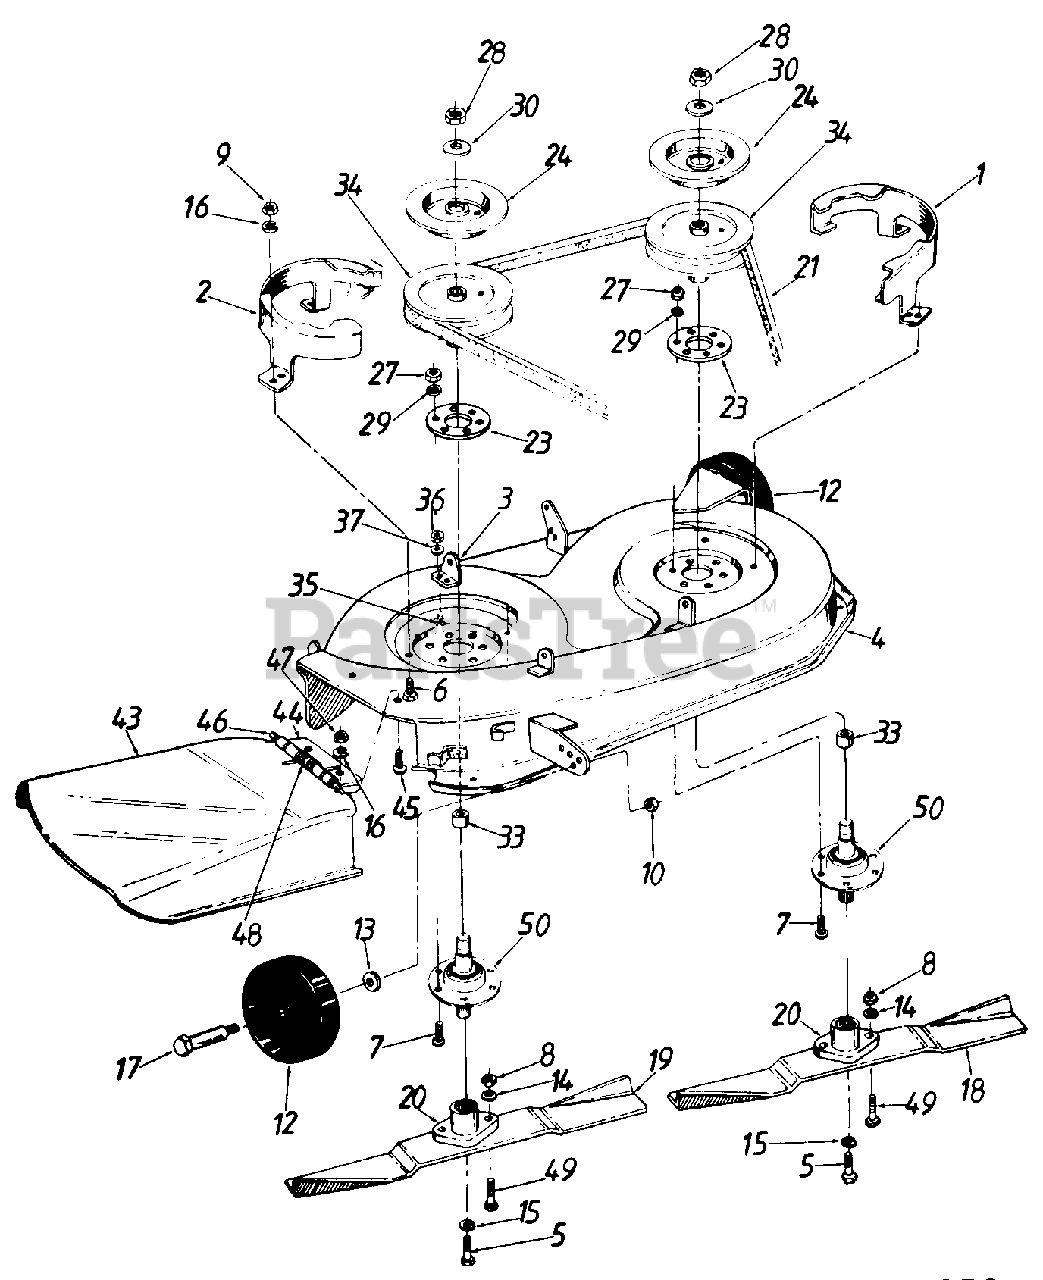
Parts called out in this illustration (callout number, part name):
5	Hex Bolt 3/8-24 x 1.0" Lg.
6	Hex Bolt 1/4-28 x .62" Lg.
7	Rib Neck Bolt
8	Hex Nut 5/16-24 Thd.
9	Hex Nut 1/4-28 Thd.
10	Hex L-Nut 3/8-16 Thd.
12	Deck Wheel
13	Bell-Wash. .380" I.D. x .88
14	L-Wash. 5/16" I.D.
15	L-Wash. 3/8" I.D. H.D.
16	Bell-Wash. .265" I.D. x .75
17	Shld. Bolt .498" Dia. x 1.53 Lg.
18	L.H High-Lift Blade
19	R.H. High-Lift Blade
20	Blade Adapter
21	V-Belt
23	Reinforcement Plate
24	Brake Disc
27	Hex Nut 5/16-24 Thd.
28	Hex Jam Nut 5/8-18 Thd.
29	L-Wash. 5/16" I.D.
30	L-Wash. 5/8" I.D.
33	Spacer
34	5" Dia. Pulley
35	Hex Scr. 1/4-20 x .62" Lg.
36	Hex Nut 1/4-20 Thd.
37	L-Wash. 1/4" I.D.
43	Chute Ass'y.
44	Chute Bracket
45	Truss-Mach. Scr. 1/4-20 x .75" Lg.
46	Hinge Pin
47	Hex Jam Nut 1/4-20 Thd.
48	Torsion Spring 1.14" Lg.
49	Hex Bolt 5/16-24 x 1.0" Lg.
50	Blade Spindle Complete
